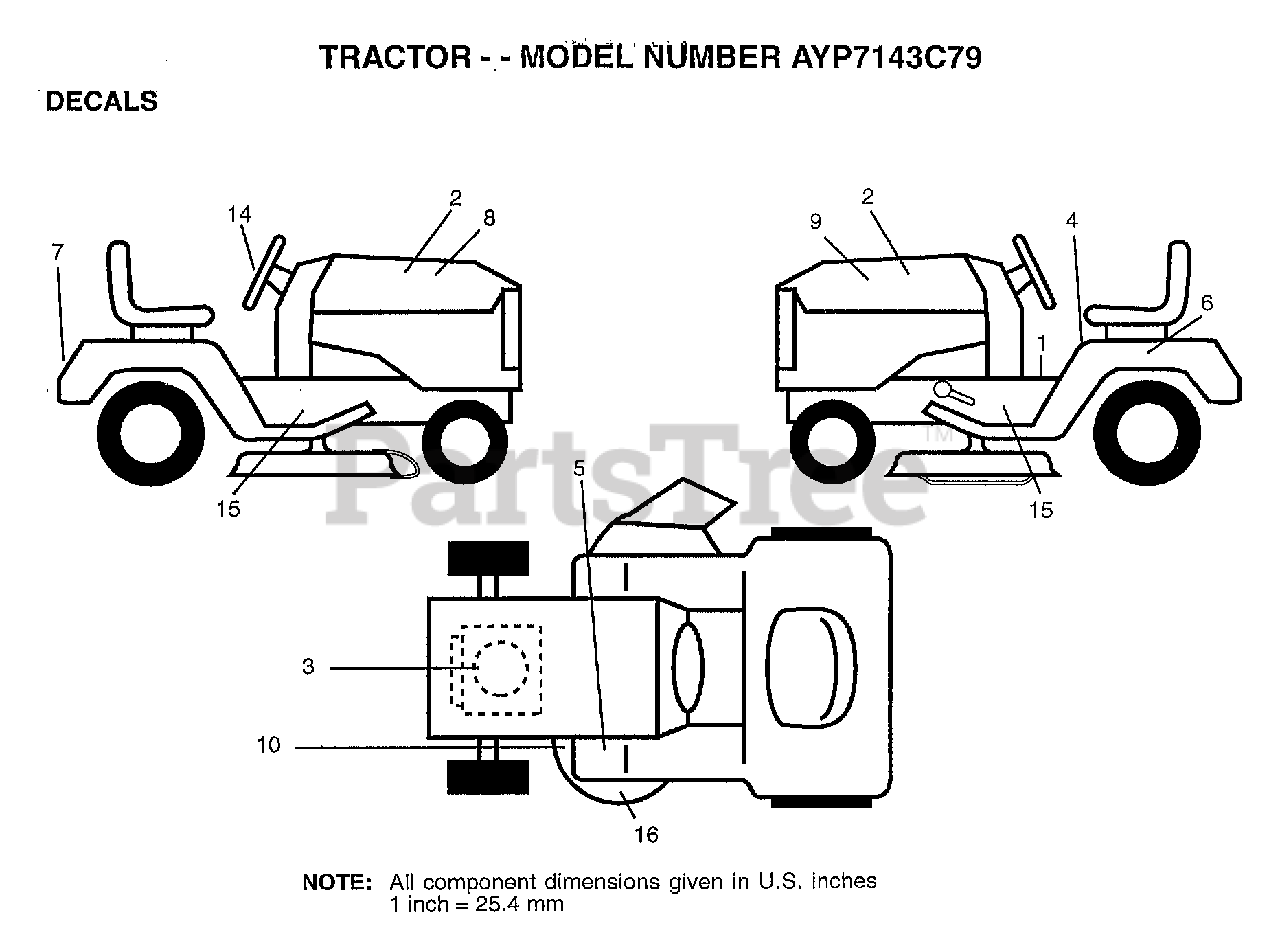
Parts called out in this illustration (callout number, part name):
1	"DECAL DASH,OPER."
2	DECAL.INS.HD.14.5
3	DECAL, ENGINE
4	"DECAL DANGER,FEND"
6	DECAL.BATRY.3-3908
8	DECAL.HD.RH.WIZAR
9	DECAL.HD.LH.WIZAR
10	DECAL
14	DECAL.INS.STRG.WL
15	DECAL CHASSIS WIZ
16	DECAL DECK WIZ +
